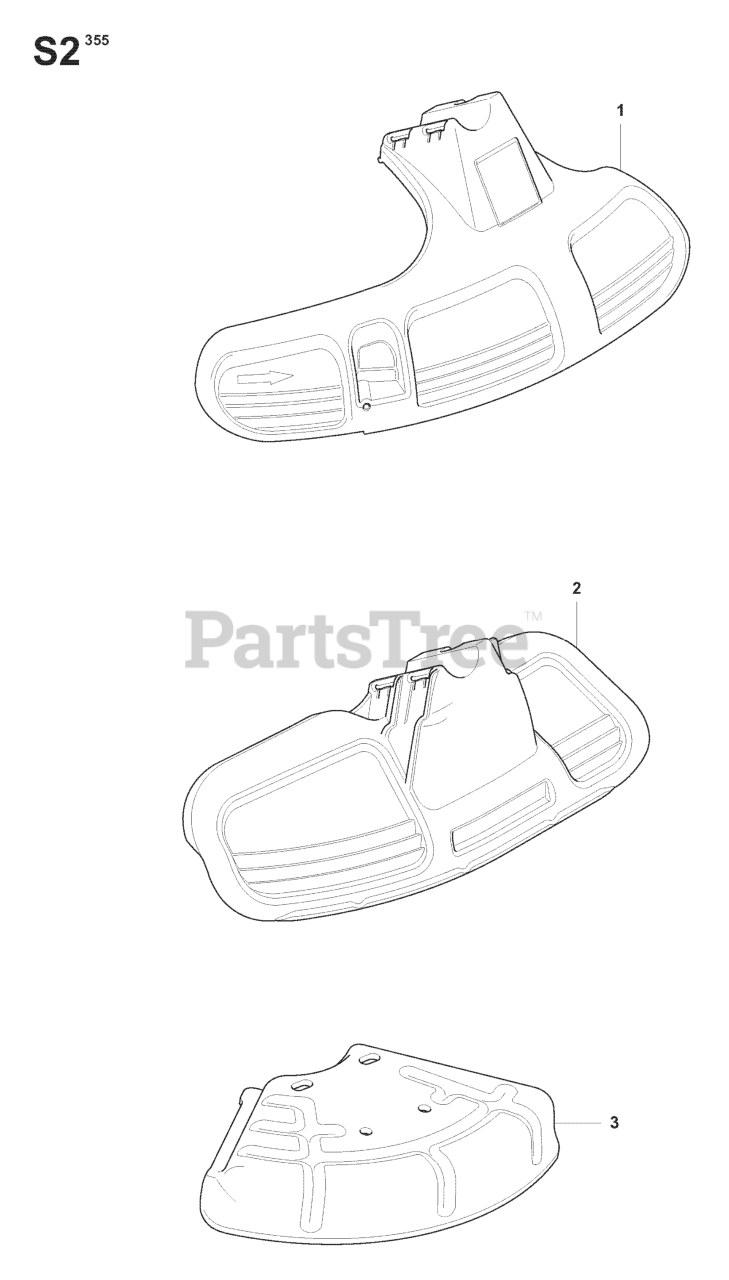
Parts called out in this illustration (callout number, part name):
1	PROTECTION
2	BLADE GUARD GRASS
3	BLADE GUARD SAW
